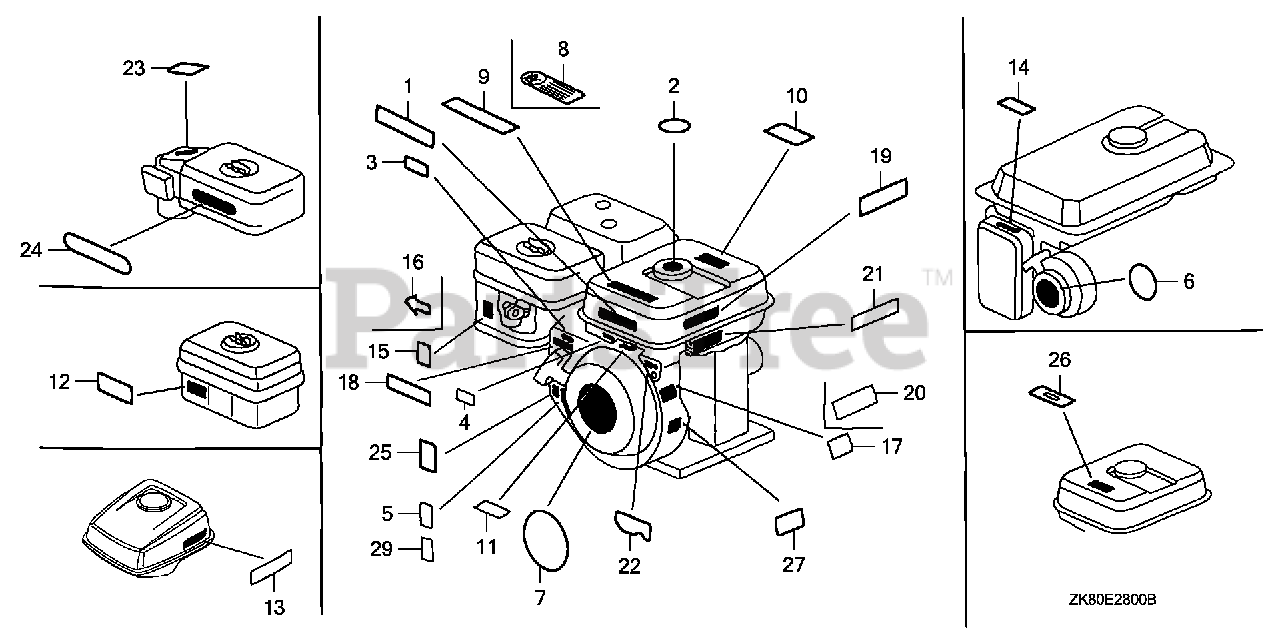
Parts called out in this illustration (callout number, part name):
4	LABEL, E-SPEC (15.5X27.5)
7	EMBLEM (GX160)
9	LABEL, CAUTION (ENGLISH, ETC.)
15	MARK, CHOKE
19	MARK, OIL ALERT (ENGLISH)
